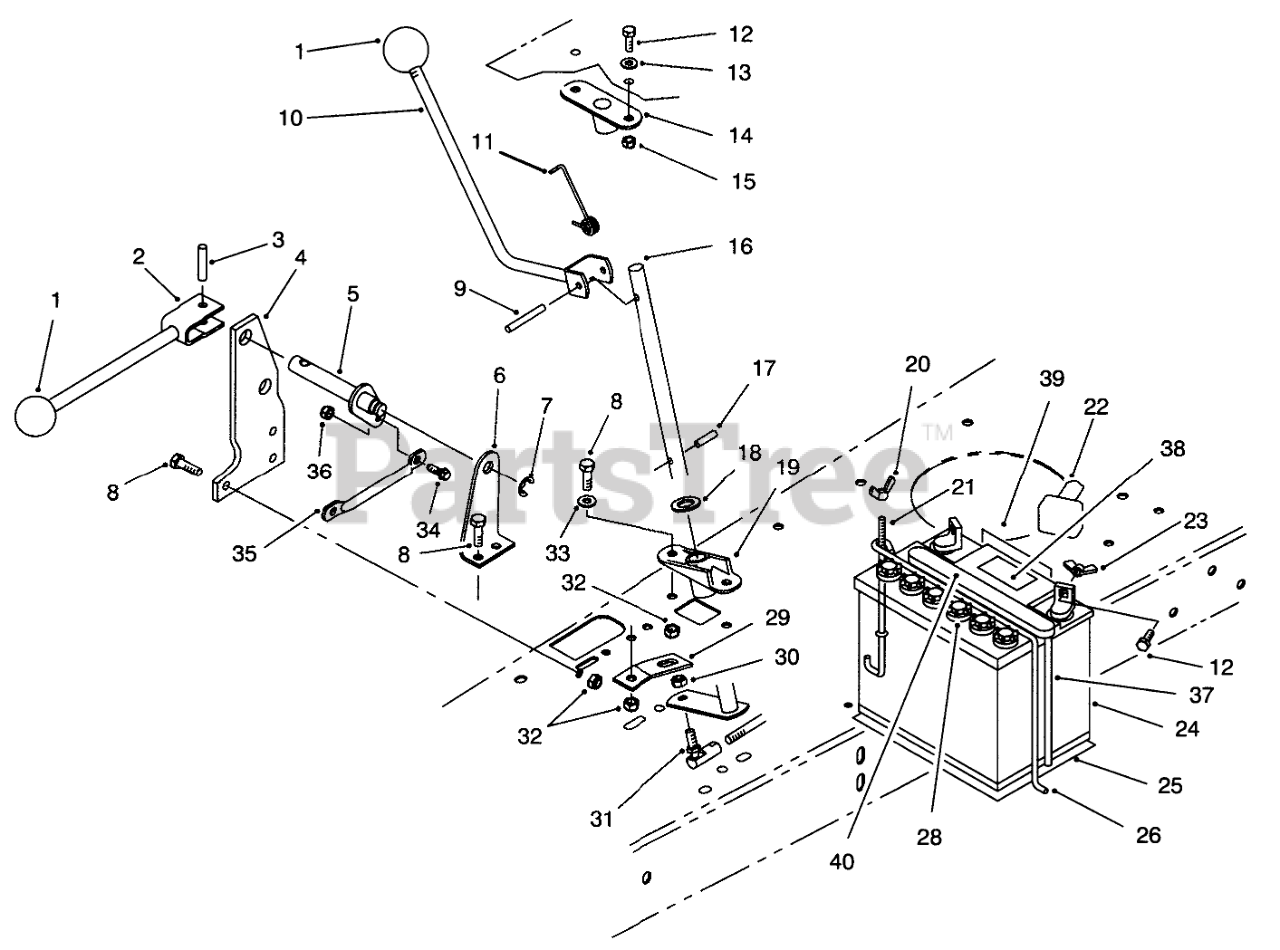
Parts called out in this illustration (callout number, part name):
2	Lever W.A.-Engage
3	PIN-ROLL
4	Pivot-Outer
5	PIVOT SHAFT WA
6	Bracket-Pivot, Inner
7	RING-RETAINING, EXTERNAL
8	SCREW-HH
9	PIN-ROLL
10	Lever W.A.-Shaft
11	SPRING-TORSION
12	SCREW-HH
13	WASHER-FLAT
14	SUPPORT-SHIFT SHAFT
15	NUT-LOCK, NI
16	SHAFT-SHIFT
17	PIN-SPRING
18	WASHER-THRUST
19	SUPPORT-LOWER SHIFTER
20	NUT-WING
21	POST-BATTERY
22	BOOT-TERMINAL
23	NUT-WING
24	Battery-12 Volt (Incl. Ref. #28 & 37)
25	PAD-SKID, ANTI
26	HOLDDOWN-BATTERY
27	O-RING
28	CAP-BATTERY
29	RETAINER-TRACTION SPRING
30	NUT-LOCK
31	JOINT-BALL
32	NUT-LOCK, NI
33	WASHER-PLAIN
34	SCREW-SHOULDER
35	LINK-BELLCRANK
36	NUT-HEX
37	TUBE-BATT DRAIN/80-2600
38	DECAL-BATTERY
39	DECAL-DANGER
40	DECAL - DANGER
